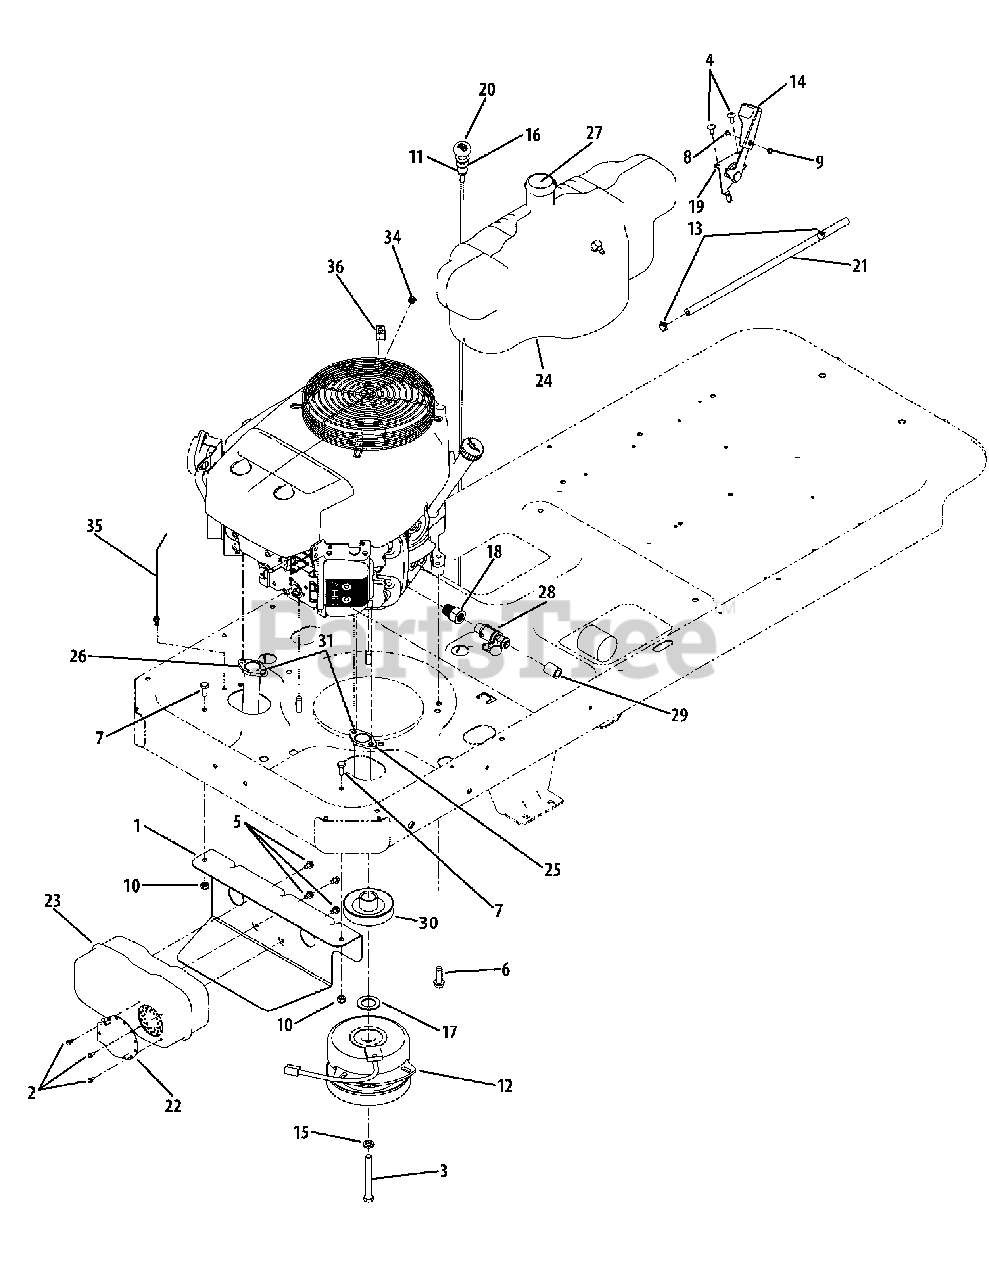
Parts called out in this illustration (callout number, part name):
1	Muffler Mounting Bracket
2	Hex Washer Head Screw, #8-18 x .5
3	Hex Cap Lock Screw, 7/16-20 x 3.5
4	Hex Washer Hd. Screw, 1/4-14 x .625
5	Hex Washer Head Screw, 1/4-20 x .5
6	Hex Washer Hd. Screw, 3/8 -16 x 1.25
7	Hex Cap Screw, 5/16-18 x .75
8	Truss Hd. Mach. Screw, #8-32 x .375
9	Hex Nut, #8-32
10	Hex Insert Lock Nut, 5/16-18
11	Hex Jam Nut, 3/8-16
12	Electric PTO Clutch Assembly
13	Hose Clamp
14	Throttle Control Knob
15	Lock Washer,7/16
16	Flat Washer, .406 x .875 x .059
17	Flat Washer, 1.031 x 1.62 x .095
18	Hex Fitting
19	Throttle Cable, 34.25 LG
20	Choke Cable, 61 LG
21	Fuel Line Hose
22	Muffler Deflector
23	Muffler
24	Fuel Tank
25	Exhaust Pipe, RH
26	Exhaust Pipe, LH
27	Fuel Cap
28	Oil Drain
29	Oil Drain Extension Hose
30	Drive Pulley
31	Muffler Gasket
34	Sems Nut, 1/4-20
35	Push Mount Cable Tie
